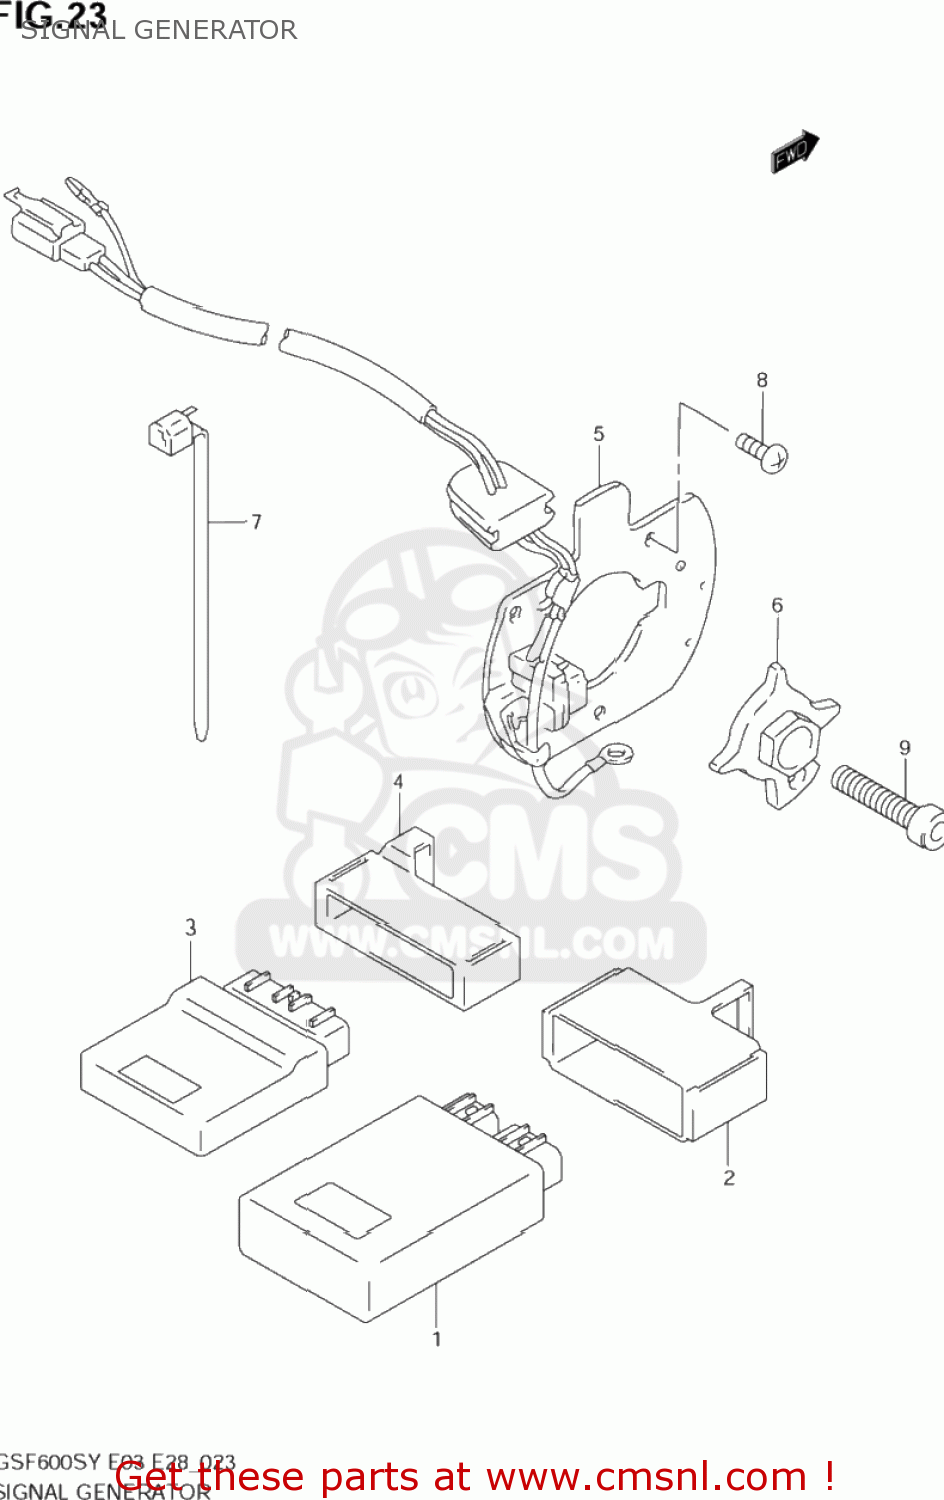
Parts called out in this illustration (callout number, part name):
1	IGNITOR ASSY
2	CUSHION,IGNITOR
3	IGNITOR ASSY
4	COVER,IGNITOR
5	STATOR,SIGNAL GENERATOR
6	ROTOR,SIGNAL GENERATOR
7	CLAMP(L:125)
8	SCREW
9	BOLT
